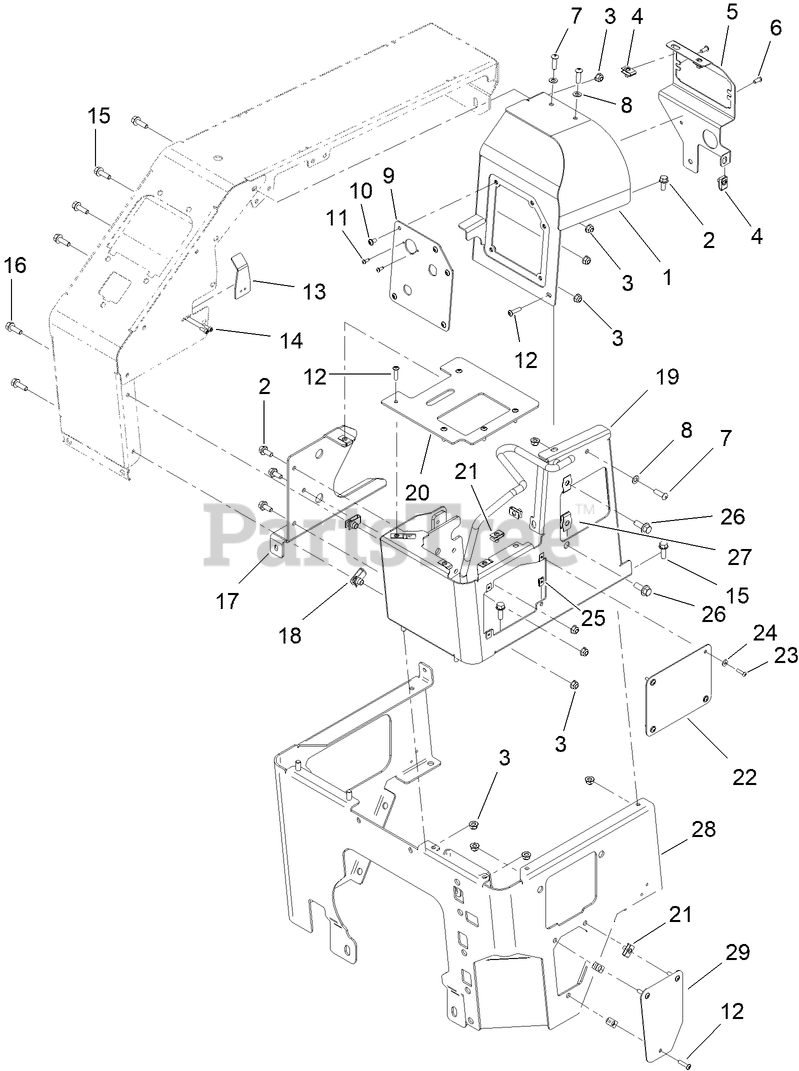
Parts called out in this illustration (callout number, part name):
1	CONSOLE COVER-RIGHT (TORO RED)
2	SCREW-HHF
3	NUT-HF, NI
4	NUT-U
5	MOUNT BRACKET-FUSE
6	SCREW-HHF
7	SCREW-HSBH
8	Washer-Flat
9	DOOR (TORO RED)
10	FLG SCREW (M6 X 12MM) BUTTON HEAD 8.8
11	SCREW-PPH
12	SCREW-HSBH
13	PLATE-THREADED
14	BOLT (#10-32 X 1/2" SOC SS)
15	SCREW-HHF
16	SCREW-HHF
17	PLATE-HYDRAULIC TANK
19	CONSOLE-TOP (TORO RED)
20	PLATE-CONTROLS TOP (TORO RED)
22	COVER-TRENCHER (TORO RED)
23	SCREW-HSBH
24	WASHER-FLAT
25	NUT-SPEED
26	SCREW-HHF
27	NUT-TINNERMAN
28	CONSOLE-LOWER
29	COVER-ACCESS
